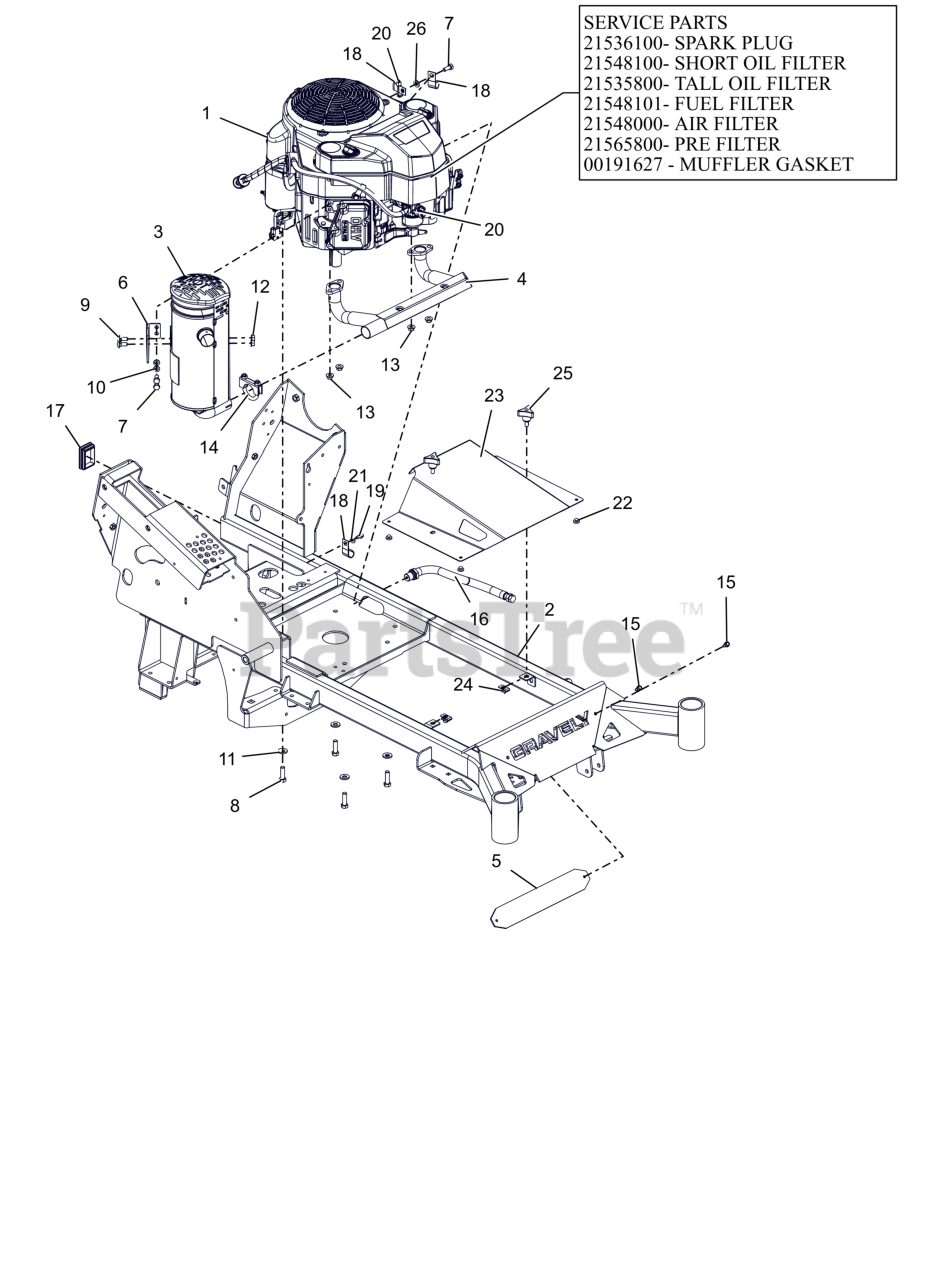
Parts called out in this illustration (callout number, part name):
1	ENG. KAW FS600
1	PLUG, SPARK
1	OIL FILTER, KAWASAKI FR
1	FILTER,OIL - KAW
1	FUEL FILTER-KAWASAKI FR
1	AIR FILTER, KAWASAKI FR
1	PRE FILTER, KAWASAKI FS
1	GASKET, MUFFLER S/O
2	WLDMT, PRO STANCE 36" FRAME
3	MUFFLER, PROSTANCE
4	MANIFOLD PRO STANCE 32-36" EXHAUST
5	BACK, NAMEPLATE
6	BRKT, MUFFLER MOUNT - FT730
7	BLT, HEX M8-1.25X20 G8.8 ZCC
8	BLT, HEX .38-16X1.25 G5 ZCC NT
9	BLT,RHSN .31-18X.75 G5 ZCC
10	WSHR,LK-REG .312X.078 ZCC
11	WASHER, 3/8" SPRING DISC
12	NUT,LK-CTR-FLG .31-18 GF ZCC
13	NUT-LK-TOP-FLG M8 ZCC
14	CLAMP, MUFFLER - 1.438
15	SCR-TAP .25-20X.50 HWH ZCC
16	HOSE, OIL DRAIN
17	PLUG, RECT 1.575 x 2.362
19	SCR-TAP .25-20X.50 HWH ZCC
20	CABLE TIE, .15 X 8.50
21	WSHR,FLT .281X.625X.065 ZCC
22	BUMPER GROMMET
23	COVER, BELT (RED)
24	NUT-CLIP RETAINER 5/16-18X.56
25	KNOB,WING STUD 5/16-18 X .75
26	WSHR,FLT .344X.688X.065 ZCC
